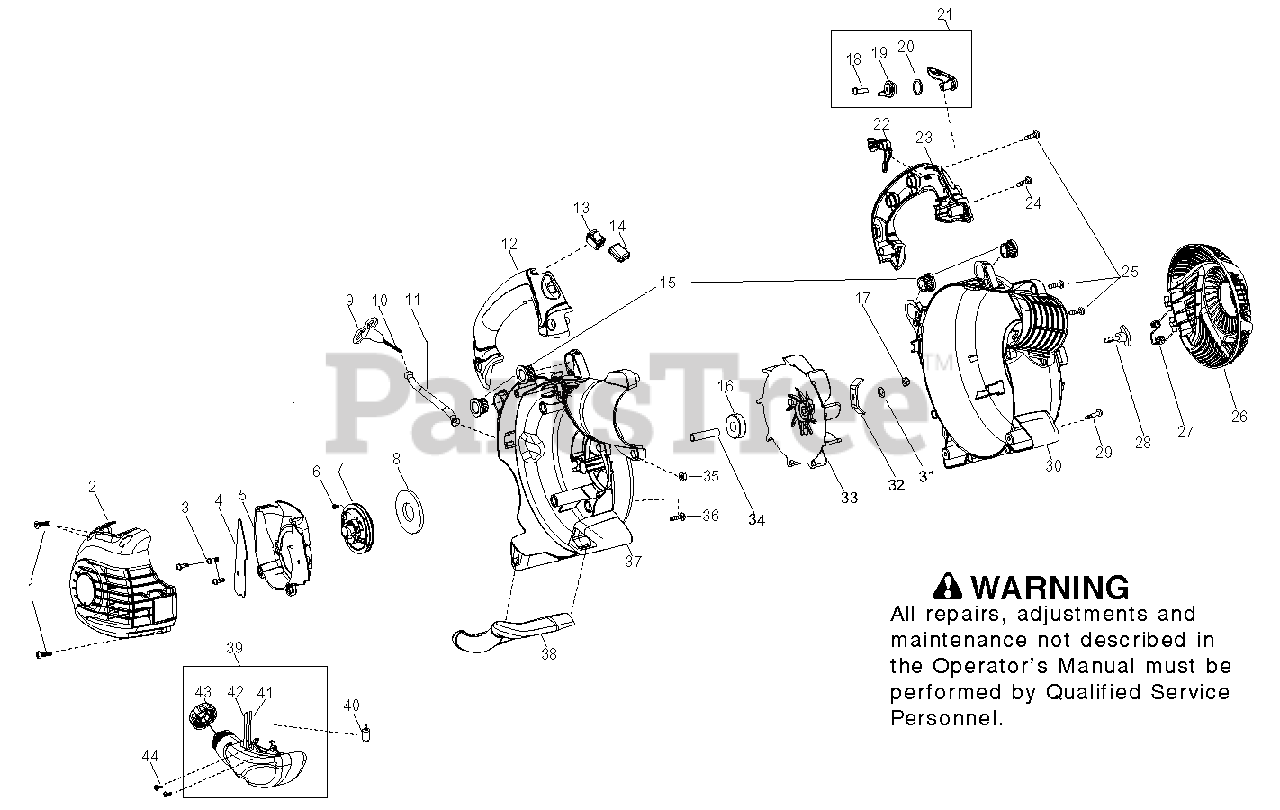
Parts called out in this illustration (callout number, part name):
4	SHIELD BAFFLE
7	KIT STARTER PULLEY
8	KIT STARTER SPRING
9	HANDLE STARTER BLK
10	KIT ROPE
11	TUBE STARTER ROPE
12	HANDLE RH W/SOFT GRI
13	KIT SWITCH
14	Protector Switch
16	Hub Bearing
19	RATCHET CRUISE CONTRO
21	KIT CRUISE CONTROL
22	TRIGGER THROTTLE BLA
23	HANDLE LEFT W/SOFT GRIP
24	SCREW #10 PLASTITE 1.362
26	COVER VAC DOOR
27	SPRING VAC DOOR
28	KNOB BLOWER
30	ASSY SCROLL LEFT AV
31	LOCK WASHER
32	BLADE MULCH
33	ASSY IMPELLAR HUB
34	FLYWHEEL SPACER
37	ASSY SCROLL RIGHT W/BEARING
38	HANDLE ASSIST VAC BL
39	FUEL TANK ASSY
40	FUEL PICK-UP ASSY
42	LINE KIT
43	FUEL CAP ASSY
44	SCREW FUEL TANK RETAINER
